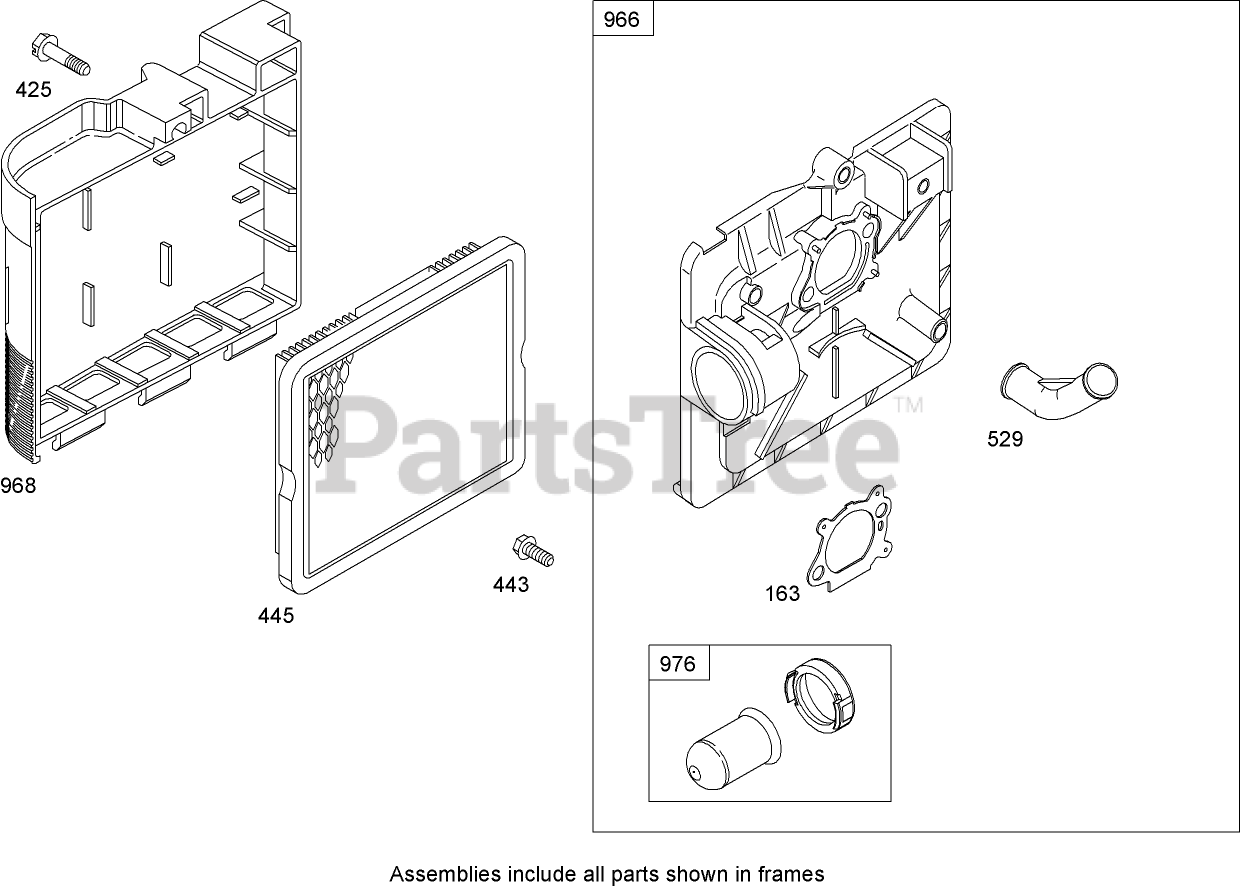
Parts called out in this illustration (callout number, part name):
163	Gasket-Cleaner, Air
425	Screw
443	Screw
445	Filter-Cartridge, Air Cleaner
529	Grommet
966	Base-Primer, Air Cleaner
968	Cover-Cleaner, Air
976	Primer-Carburetor
